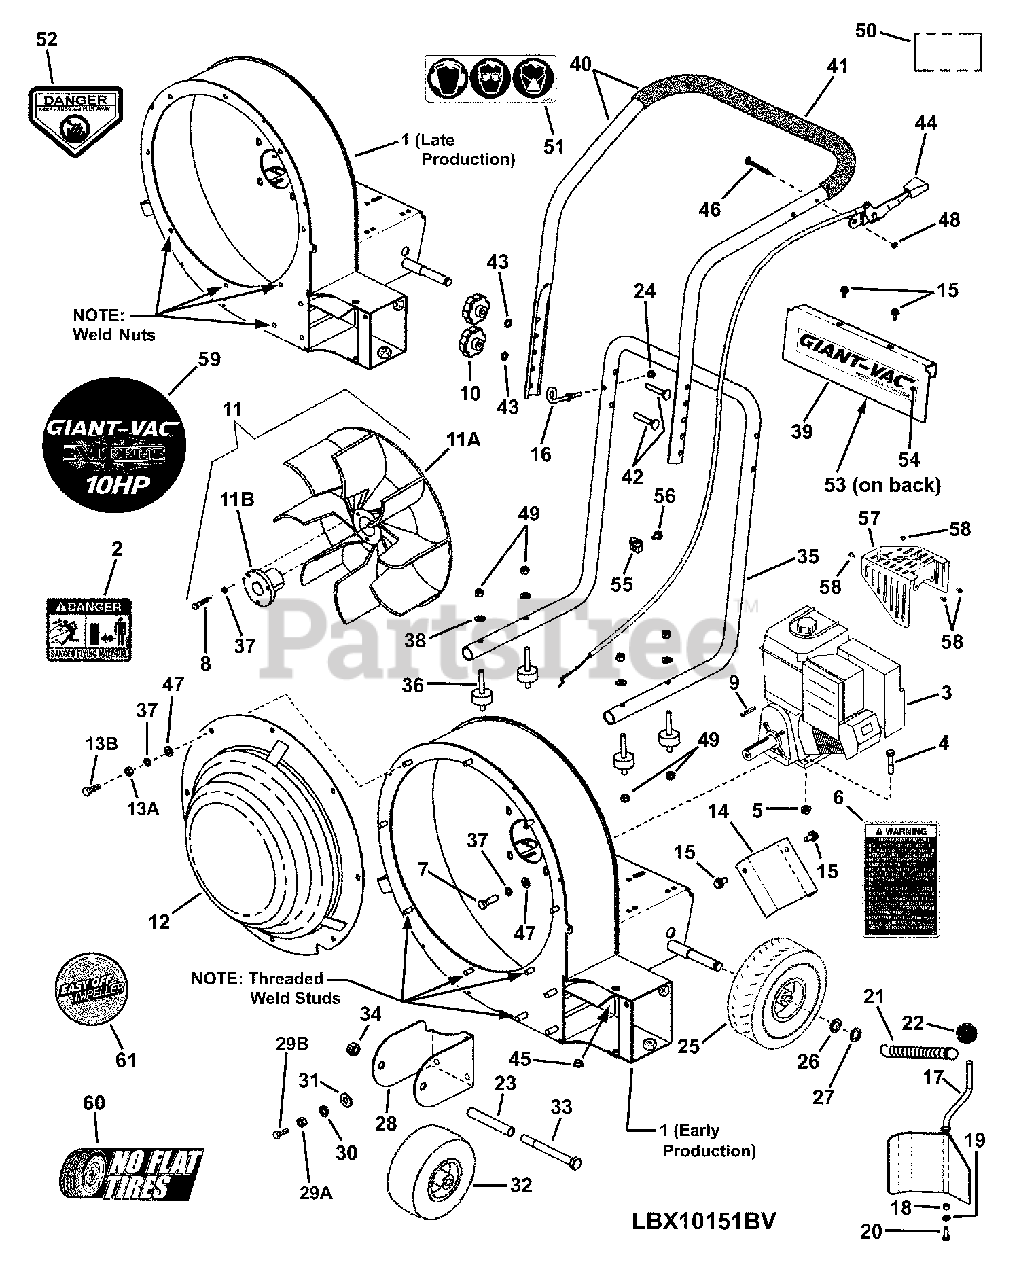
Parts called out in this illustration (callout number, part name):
1	WELDMENT, Housing - Extreme Blower
2	DECAL, Thrown Objects, Large
3	* ENGINE, B&S 10HP Mod 205412-0121-E1
4	SCREW, 5/16-18 x 1-1/2 Hex Head Cap, GR 5
5	NUT, 5/16-18 Hex Flange Lock, GR 5
6	DECAL, Warning - Leaf Blower
7	SCREW, 5/16-24 x 1" Hex Head Cap, GR 5
8	SCREW, 5/16-18 x 1-1/4", Hex Head Cap, GR 5
9	KEY, 1/4" Square x 1-7/16"
10	KNOB, Fluted (5/16-18 thread)
11	ASSEMBLY, 15" 9 Blade Impeller
11A	IMPELLER, Cast, 15" O.D.
11B	HUB, Taper-Lok, Type 1 - P1 x 1.125
12	WELDMENT, Intake Baffle - Extreme
13A	NUT, 5/16-18 Hex, GR 5 or B
13B	SCREW, 5/16-18 x 3/4" Hex Head Cap, GR 5
14	DEFLECTOR, Side Air
15	SCREW, 5/16-18 x 5/8" Hex Washer Self-Tap
16	GUIDE, Rope (1/4-20 thread)
17	** WELDMENT, Door Front/Side Discharge
18	BUSHING, Steel .250 IDx.375 ODx.25 Long
19	WASHER, 1/4" Split Lock
20	SCREW, 1/4-20 x 3/4" Hex Head Cap, GR 5
21	SPRING, Extension
22	KNOB, Ball - 3/8-16 Metal Insert
23	TUBE, Front Wheel - Extreme
24	NUT, 1/4-20 Hex Center Lock, GR 5 or B
25	ASSY., Wheel & Tire 4.10/3.50-4 "Flatfree"
26	WASHER, .64 x .99 x .05 Flat
27	RING, External Retaining
28	BRACKET, Front Wheel Mounting
29A	NUT, 3/8-16 Hex, GR 5 or B
29B	SCREW, 3/8-16 x 1" Hex Head Cap, GR 5
30	WASHER, 3/8" Split Lock
31	WASHER, 3/8" Flat
32	ASSY., Tire & Wheel 9 x 3.50-4 "Flatfree"
33	BOLT, 1/2-13 x 5" Hex Head Cap
34	NUT, 1/2-13 Hex Center Lock, GR 5
35	HANDLE, Lower Folding - Wide - Blower
36	MOUNT, Vibration (5/16-18, both ends)
37	WASHER, 5/16" Split Lock
38	WASHER, 5/16" Curved
39	DASH PANEL, Blower - Wide
40	ASSY, Upper Handle & Grip - Wide
41	GRIP, 1.0 x 21-1/2" Foam
42	BOLT, 5/16-18 x 2", Curved Hd. Sq. Neck
43	WASHER, 5/16" Internal Tooth Lock
44	THROTTLE CONTROL, (35/1.62) Briggs
45	BUSHING .375x.500x.25 (.625x.063 Flange)
46	SCREW, 1/4-20 x 2" Hex Head Cap, GR 5
47	WASHER, .34 x .69 x .08 Flat
48	NUT, 1/4-20 Hex Nyloc
49	NUT, 5/16-18 Hex Nyloc
50	DECAL, 10HP B&S Intek
51	DECAL, Personal Protection
52	DECAL, Danger, Cut Finger
53	DECAL, GIANT-VAC (Small)
54	DECAL, GIANT VAC
55	CASING CLAMP, B&S Intek Engine
56	SCREW, Casing Clamp - B&S Intek Engine
57	HEAT SHIELD, B&S 9 & 10 HP Intek Engines
58	SCREW, #8-18 x 1/2" Hex Head Sheet Metal
59	DECAL, 10 HP Extreme
60	DECAL, No Flat Tire
61	DECAL, Easy Off Impeller
